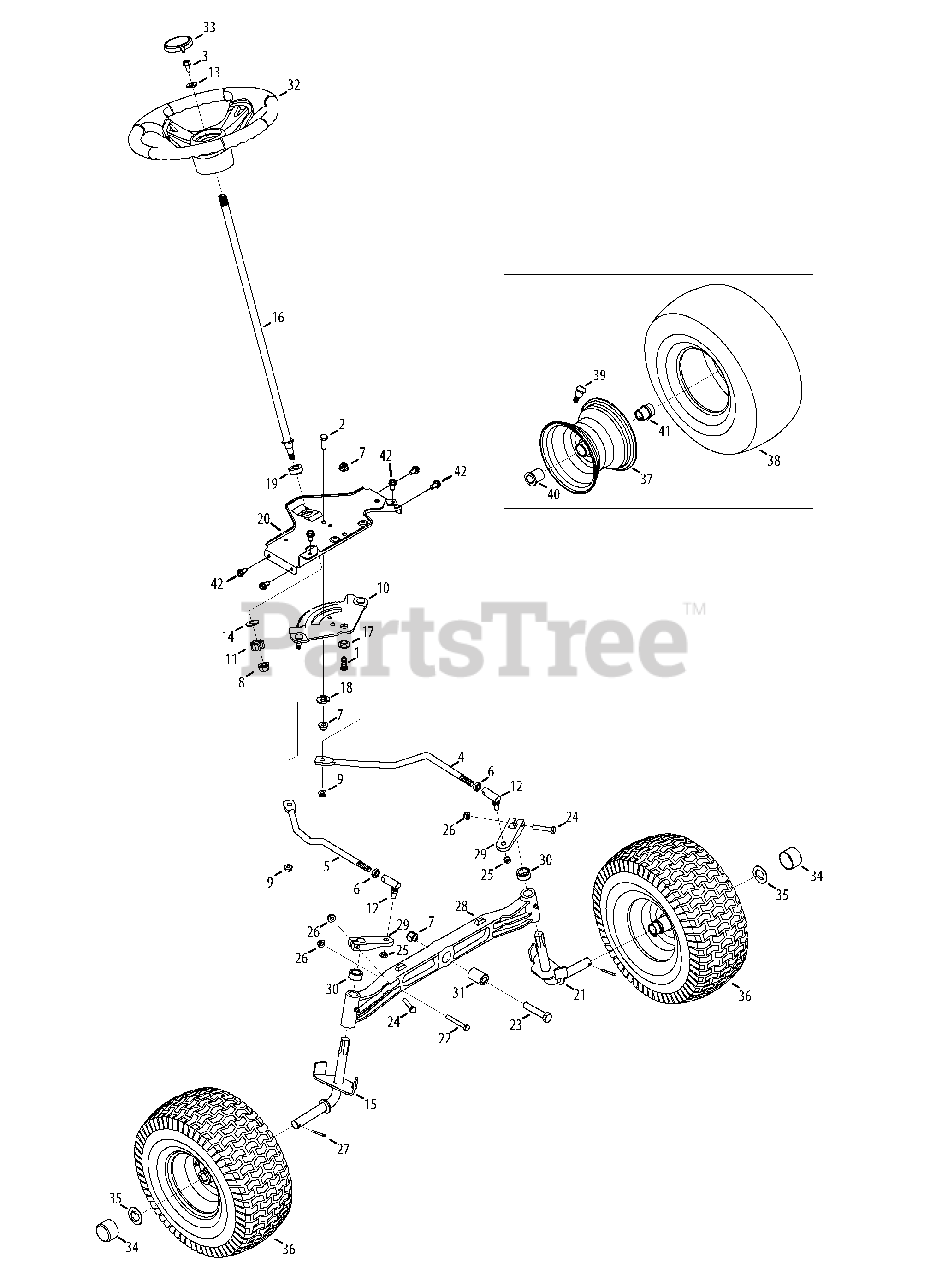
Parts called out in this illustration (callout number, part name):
1	Hex Head Screw, 3/8-16:1.00
2	Hex Head Screw, 3/8-16:1.00
3	Hex Head Screw, 5/16-18:1.00
4	LH Drag Link
5	RH Drag Link
6	Jam Nut, 7/16-20
7	Flangelock Nut, 3/8-16
8	Flangelock Nut, 7/16-20
9	Flangelock Nut, 5/16-18
10	Steering Gear
11	Steering Pinion Gear
12	Ball Joint, 7/16-20
13	Flat Washer, .406 x .875 x .105
14	Flat Washer, .51 x 1.12 x .06:HT
15	RH Axle Assembly
16	Steering Shaft, .625 OD x 24.25 LG
17	Shoulder Spacer, .385X 1.25 x .3025
18	Spacer, .38 x 1.375
19	Hex Flange Bearing 5/8 PM
20	Steering Support Bracket
21	LH Axle Assembly
22	Hex Head Screw, 5/16-18:2.25
23	Hex Head Screw, 3/8-16:2.50
24	Hex Head Screw, 5/16-18:1.75
25	Hexlock Nut, 3/8-24
26	Flangelock Nut, 5/16-18
27	Cotter Pin, 5/32:1.25
28	Pivot Bar Axle
29	Steering Block
30	Spacer, .71 ID x .125 OD x .56LG
31	Spacer, .385 x 1.00 x 1.5075
32	Steering Wheel
33	Steering Wheel Cap
34	Bumper Cap
35	Flat Washer, .781ID x 1.590OD
36	Wheel Assembly
37	Rim Assembly
38	Tire, 5 Style
39	Tubeless Air Valve
40	Flange Bearing, .760 x 1.00 x 1.20LG
41	Flange Bearing, .760ID
42	Screw, Self-tapping, 5/16-18, .750,
